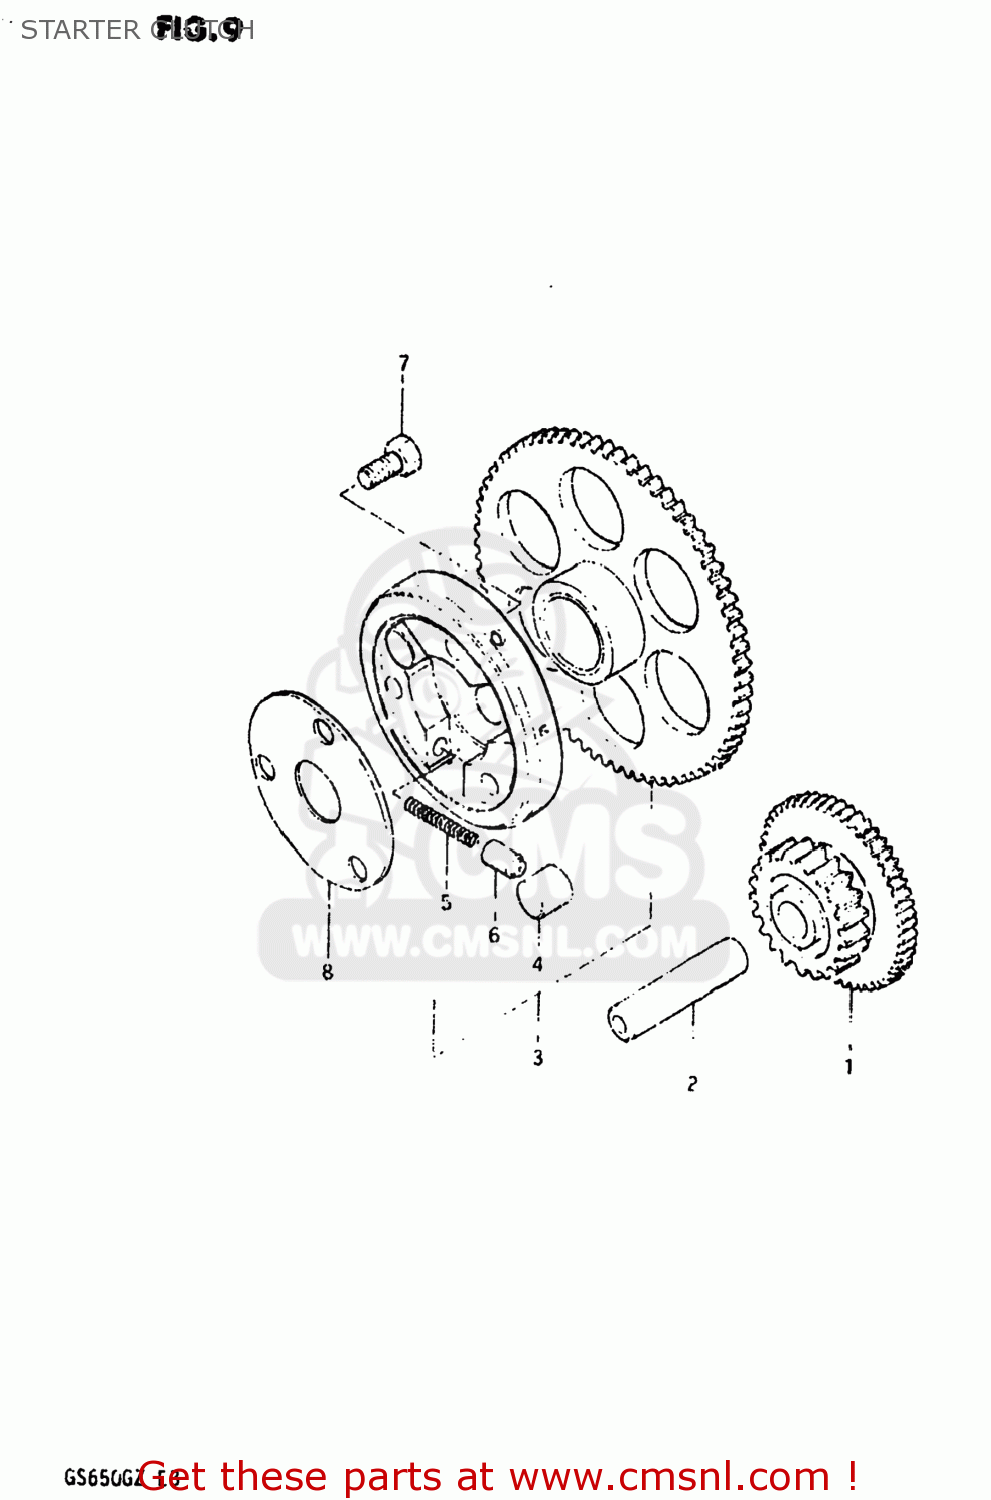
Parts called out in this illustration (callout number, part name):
1	GEAR,STARTER IDLE
2	PIN(7.4X13X56)
3	CLUTCH SET,STARTER
4	ROLLER(15X13)
5	SPRING
6	PIECE,PUSH
7	BOLT
8	SHIM,STARTER CLUTCH HUB
